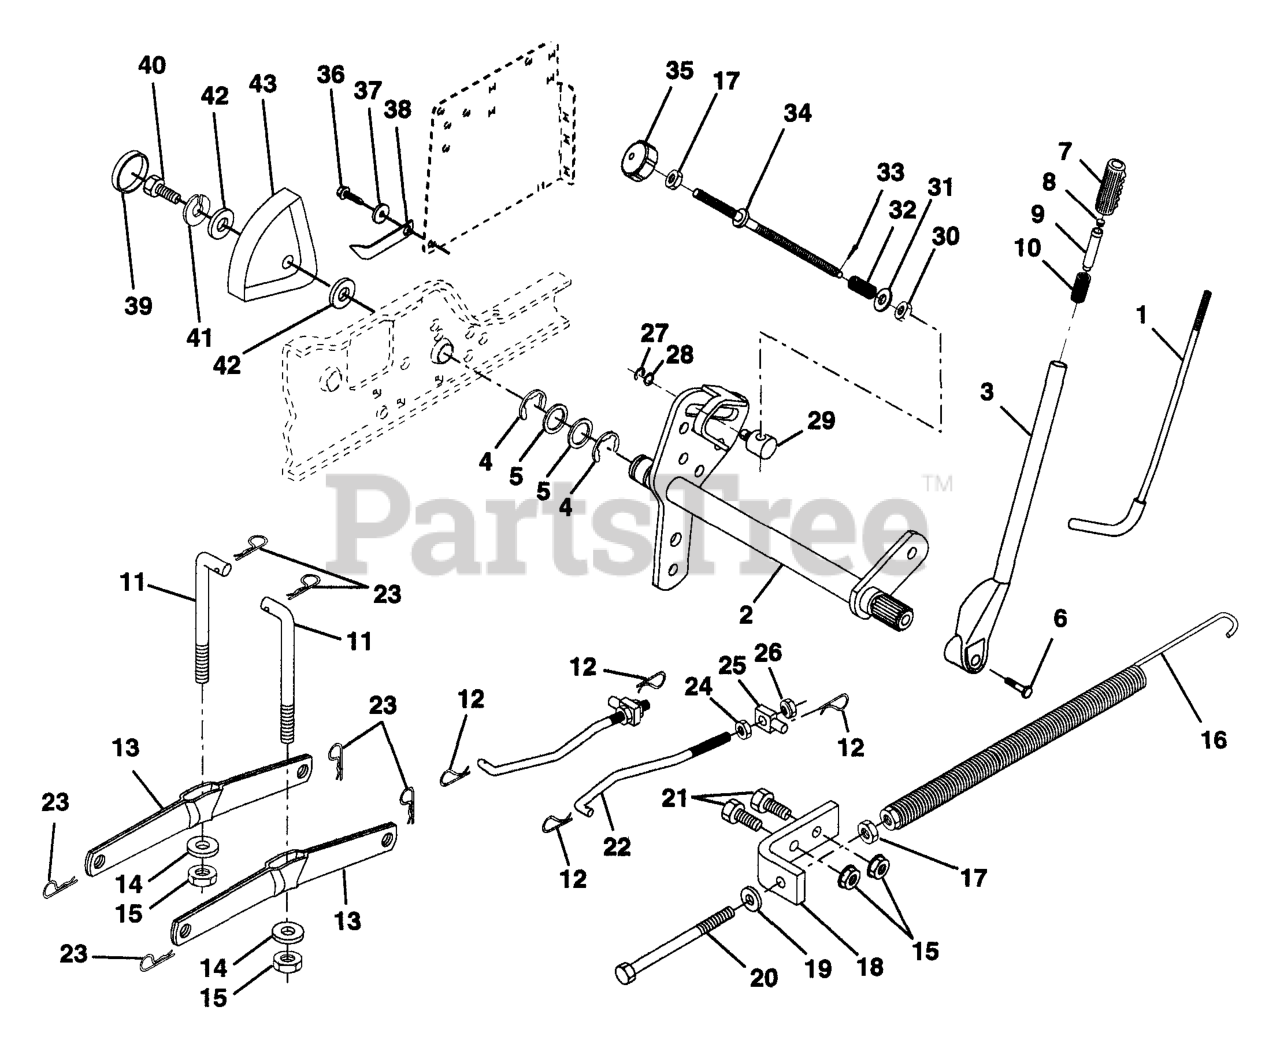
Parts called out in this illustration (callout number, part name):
1	LEVER ROD LT
2	SHAFT ASSY
3	LIFT LEVER KIT
5	Washer 29/32 x 1-1/4 x 16 Ga.
6	BOLT
7	GRIP HANDLE
8	PLUNGER BUT KIT
9	PLUNGER BUT KIT
10	SPRING**
11	LINK LIFT
12	SPRING RETAINER
13	SUSPENSION ARM
14	BEARING PIVOT
15	NUT
16	LIFT SPRING
17	NUT
18	BRKT.SPRING
19	WASHER
21	BOLT
22	FRONT LINK
23	RETAINER-SPRNG RB
24	NUT.HEX.JAM.1/2-13
25	TRUNION
26	NUT.LK.W/WSH.1/2.
27	Ring, Klip #T5304-37
28	Washer 15/32 x 3/4 x 16 Ga.
29	TRUNION LT
32	SPRING.COMP.INF.H
33	COTTER PIN
34	ROD.LIFT.ADJUSTABLE
35	KNOB INF 3/8-16
36	SCREW
38	POINTER HGT
40	BOLT.FIN.HEX.5/16-18UNC X 1.00
41	WASHER.LOCK.HVY.HLCL.SPR.5/16
43	HEIGHT INDICATOR
